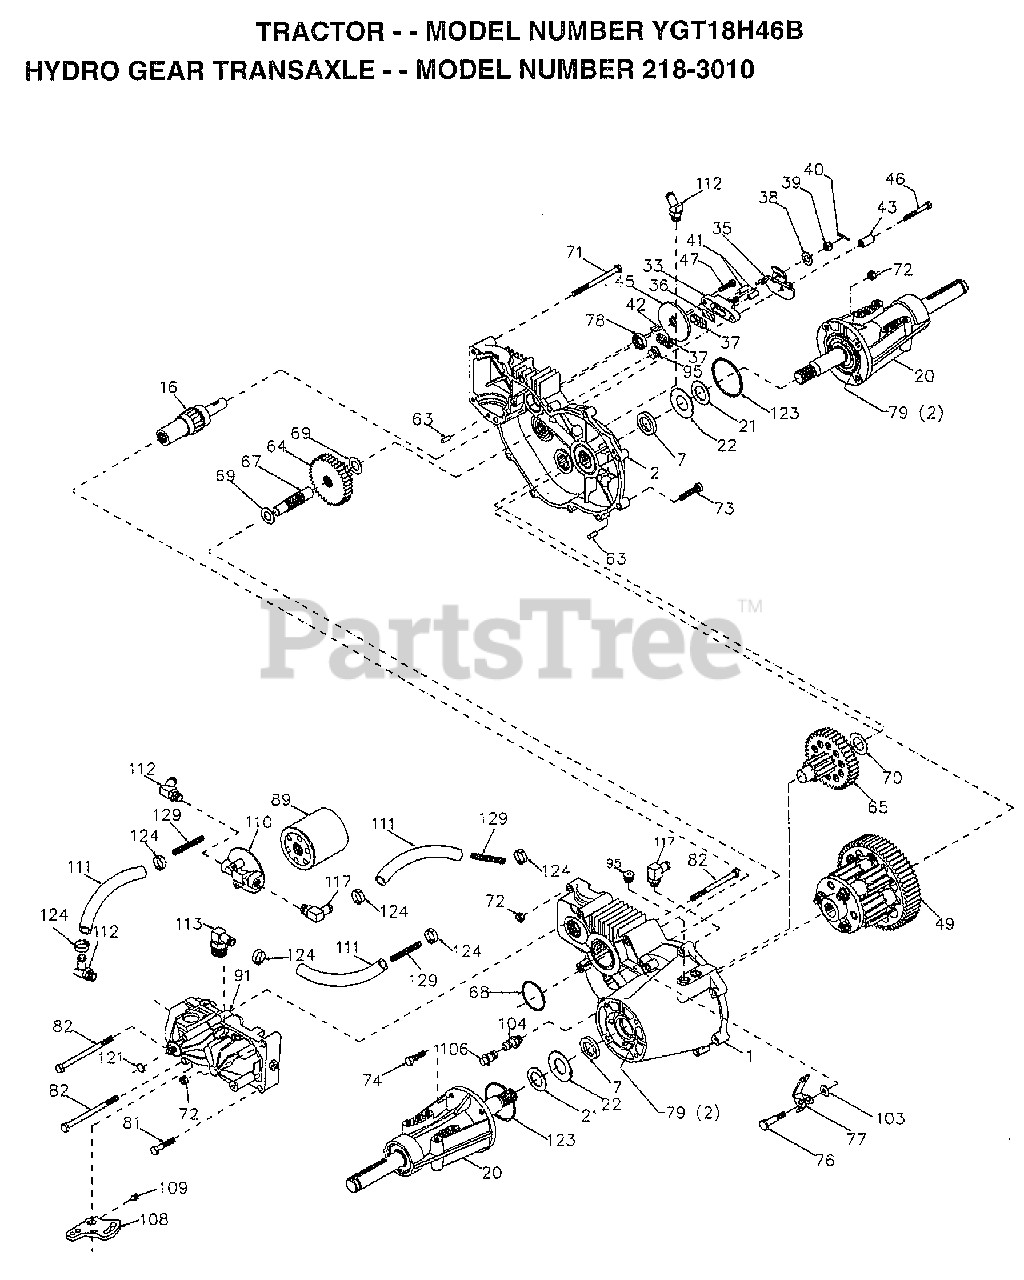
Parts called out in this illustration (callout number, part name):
1	HOUSING LH 70086
2	HOUSING RH 70088
7	SEAL.OIL.44782.HY
16	SHAFT BRAKE 62877
20	AXLE MTG 70087
21	WASHER 44805
22	WASHER 44806
33	YOKE.BRAKE.62589
35	ARM BRAKE 50214
36	PUCK PLATE 44134
37	PUCK BRAKE 44132
38	WASHER HYD 44130
41	PIN BRAKE 44127
42	KEY HI PRO 44143
43	SPACER 50259
45	DISC BRAKE 44090
46	BOLT 1/4-20 44276
47	BOLT 1/4-20 44433
49	DIFFRENTIAL.70251
63	PIN DOWL 44757
64	GEAR.14-38.44776
65	PINION DRIV 70051
67	SHAFT-44779
68	O RING 44781
69	WASHER 44795
70	WASHER 44794
71	BOLT 5/16 44827
72	LOCKNUT.43064
73	BOLT 5/16 44841
74	SCREW 5/16 45089
76	BOLT SHOULD 44785
77	ARM FREEWHL 44786
78	SEAL.OIL.44761
81	BOLT 5/16 43084
82	BOLT 5/16 44820
89	FILTER SPIN 50037
91	PUMP.BDU-10L-122
95	PLUG.9005110-5600
96	FITTING.SAE.50257
103	WASHER.50169
104	CAP.VENT.70109
106	O-RING.ASM.70110
108	ARM.CONTROL.45007
109	SCREW.SET.50018.
110	FILTER.HEAD.50207
111	HOSE.50632
112	FITTING.SAE.50604
113	FITTING.SAE.50592
117	FITTING.SAE.50589
123	O-RING.50405
124	CLAMP.50590
129	SPRING.LONG.50667
